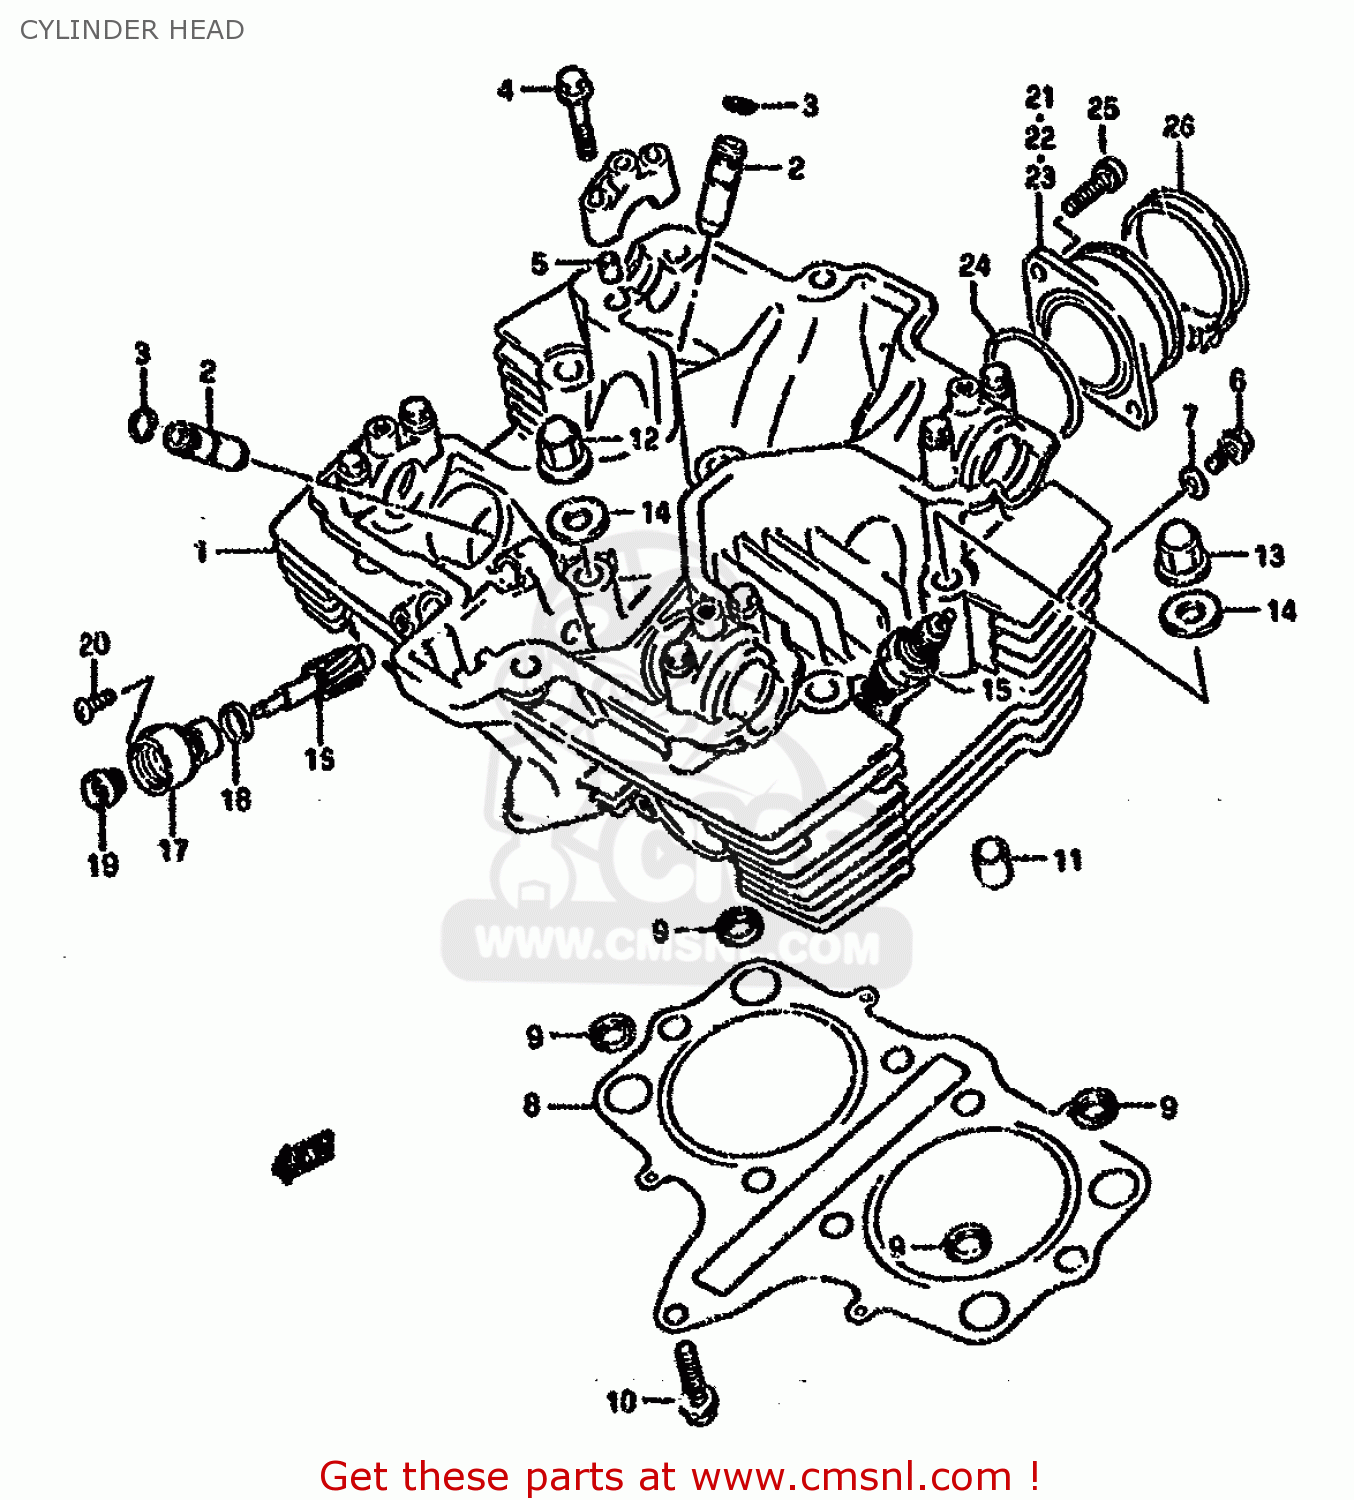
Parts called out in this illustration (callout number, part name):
1	HEAD ASSY,CYLINDER
2	GUIDE,INTAKE VALVE
3	RING,SNAP
4	BOLT(6X39)
5	PIN(6.2X8X11)
6	BOLT
7	GASKET(5.8X13X1.2) (NAS)
8	GASKET,CYLINDER HEAD (NAS)
9	O RING,HEAD GASKET
10	BOLT
11	PIN
12	NUT
13	NUT
14	GASKET(10.5X22X2) (NAS)
15	PLUG,SPARK(DPR8EA-9)
16	GEAR,TACHOMETER DRIVEN
17	SLEEVE,TACHOMETER DRIVE GEAR
18	SEAL,TACHOMETER DRIVEN
19	SEAL,OIL(5X12X8)
20	SCREW(5X12)
21	PIPE COMP,INTAKE
22	PIPE,INTAKE NO.1
23	PIPE,INTAKE NO.2
24	O-RING (D:2.4 ID:39.7)
25	SCREW
26	CLAMP
